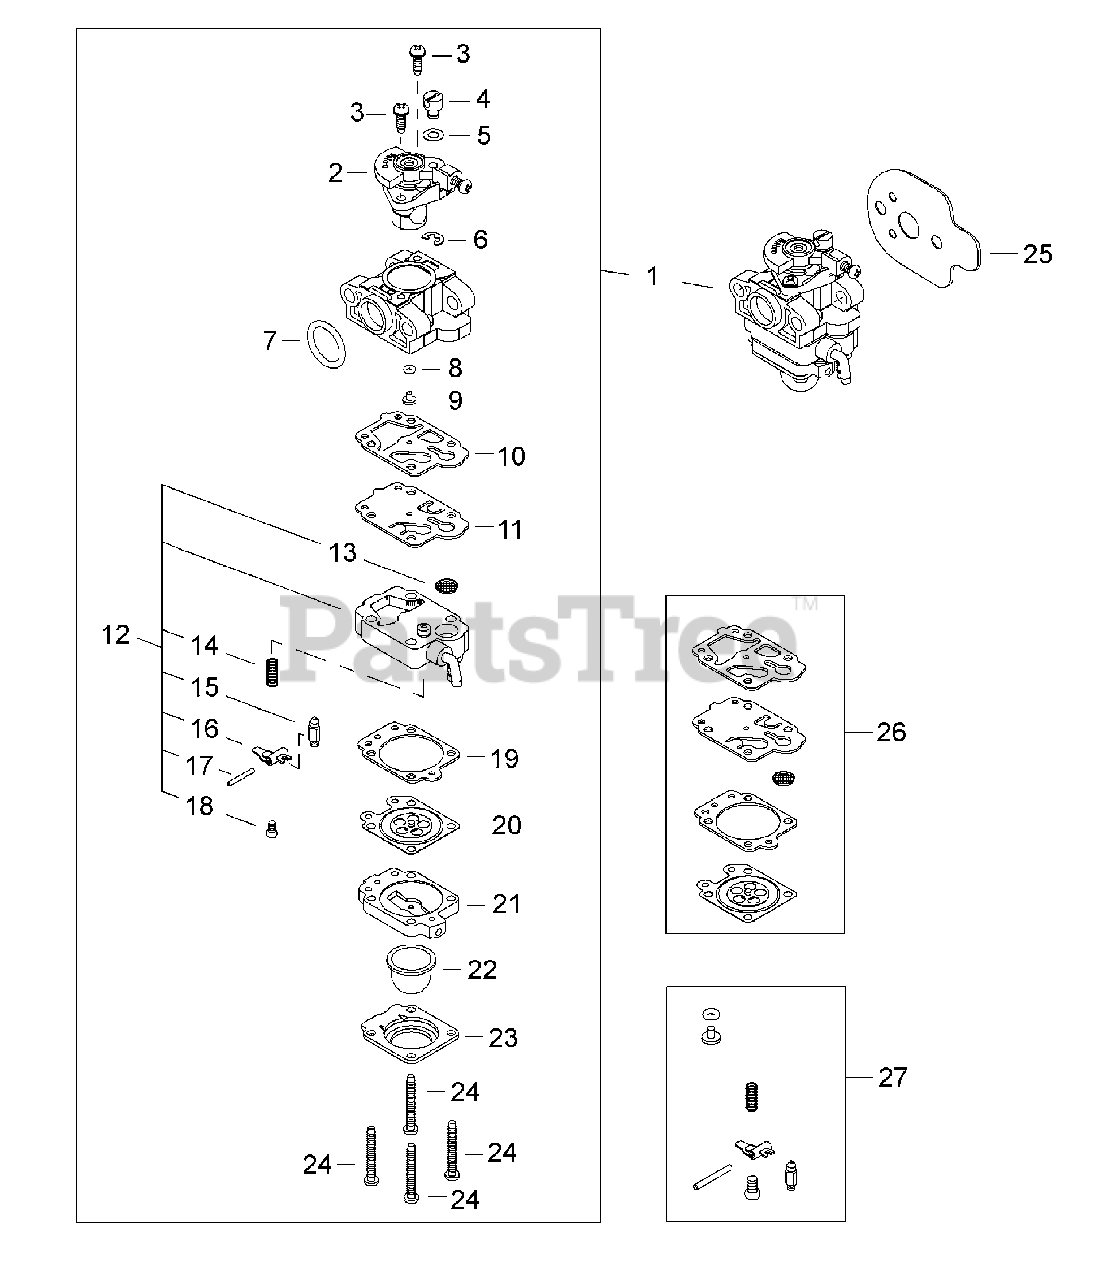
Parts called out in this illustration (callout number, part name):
1	CARBURETOR
2	THROTTLE VALVE ASSY
3	SCREW
4	SWIVEL
5	WASHER
6	RING, RETAINING
7	O-RING - 15
8	O-RING
9	JET, MAIN
10	GASKET, PUMP
11	DIAPHRAGM, PUMP
12	PUMP BODY ASSY
13	STRAINER
14	SPRING, METERING LEVER
15	VALVE, INLET NEEDLE
16	LEVER, METERING
17	PIN, METERING LEVER
18	SCREW, METERING LEVER PIN
19	GASKET, METERING
20	DIAPHRAGM, METERING
21	BASE, PURGE
22	BULB, PURGE
23	RETAINER, PURGE BULB
24	SCREW, PUMP COVER
25	GASKET, INTAKE
26	DIAPHRAGM/GASKET KIT
27	INLET NEEDLE VALVE KIT
